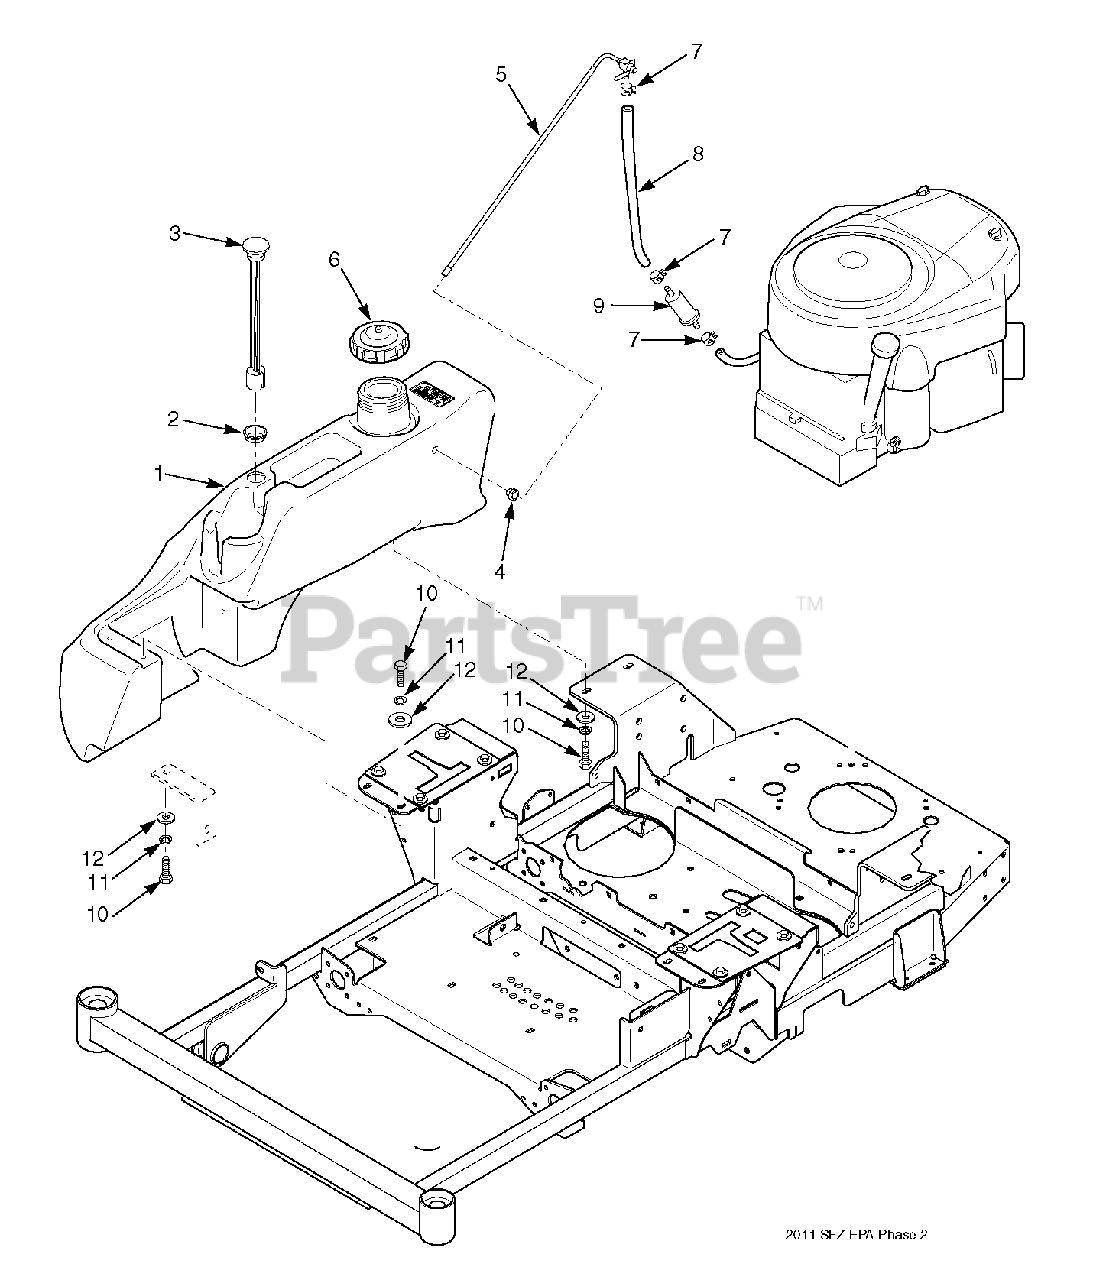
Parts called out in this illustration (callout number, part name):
1	Fuel Tank Assembly
2	Grommet
3	Fuel Gauge Assembly
4	Bushing, 0.56 Dia Viton
5	Fuel Tube Assembly
6	Fuel Cap
7	Clamp, Fuel Hose 1/4"
8	Fuel Hose, 1/4" ID Non-Perm
9	Fuel Filter
10	Bolt, Hex Head 5/16-18 x 3/4"
11	Lockwasher, 5/16" Spring
12	Flatwasher, 5/16-.375 x .875 x .083
